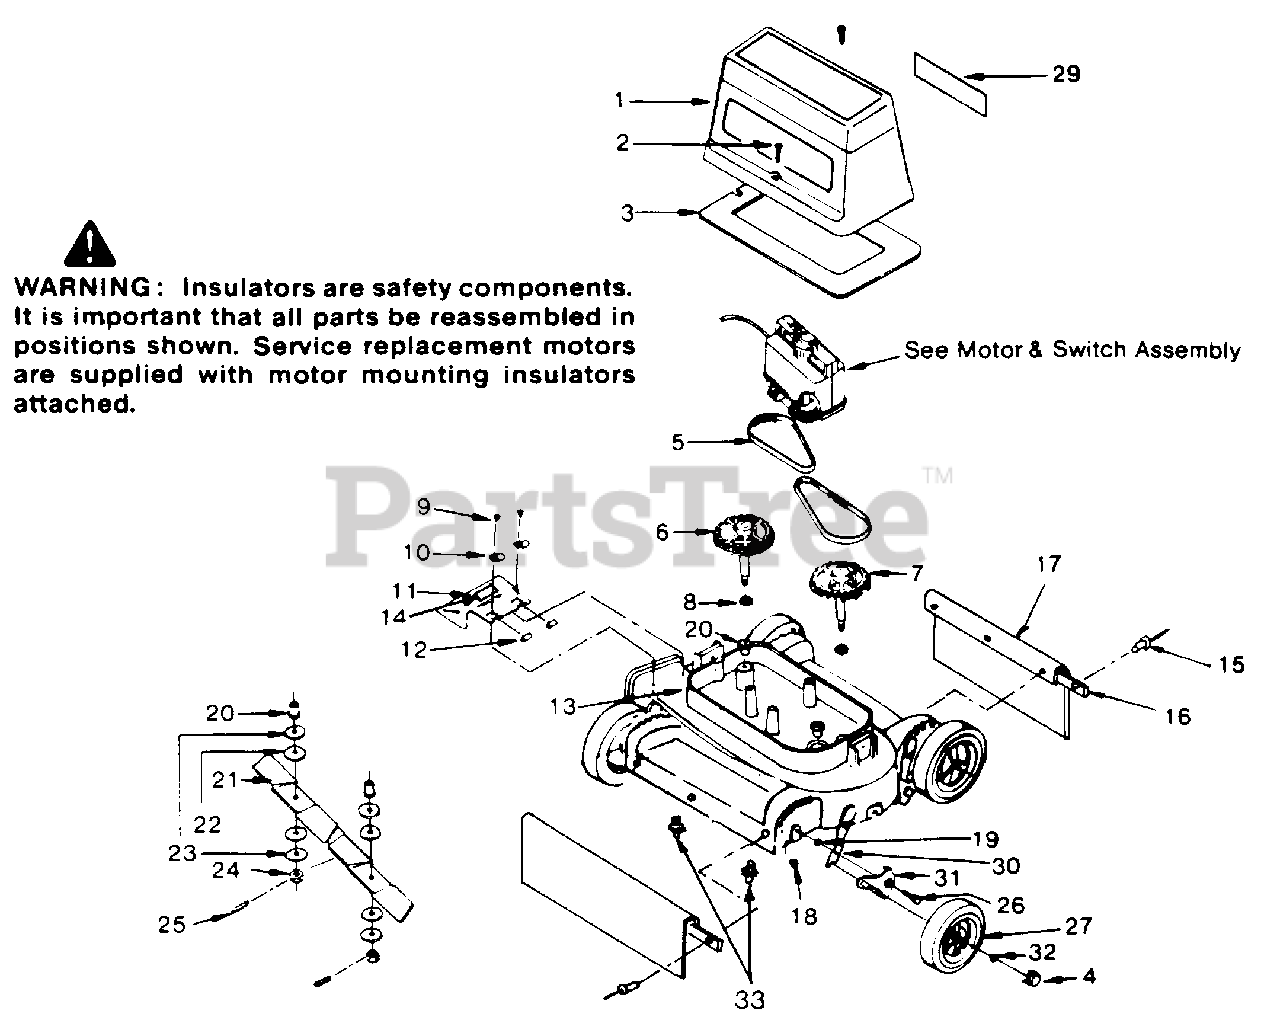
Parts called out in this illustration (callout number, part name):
1	Motor Cover
2	Screw Motor Cover
3	Baffle Air
4	Hub Cap
5	Belt-Drive
6	Blade Shaft/Pulley Long
7	Blade Shaft/Pulley Short
8	Washer, Pulley
9	Rivet, Blind
10	Hinge, Chute Guard
11	Chute Guard
12	Hinge Pin
13	Deck Assembly
14	Label - Danger
15	Rivet - Blind
16	Strap - Trail Shield
17	Trailing Guard
18	Nut 5/16 - 18 Locking
19	Washer, Axle
20	Bearing, Blade Shaft
23	Washer, Flat
24	Nut, Blade
25	Cotter Pin
26	Shoulder Bolt
27	Wheel
29	Caution & Data Label
30	Handle Height Adjustment
31	Bracket & Axle Assembly
32	Retaining Ring
33	Grease Fitting
